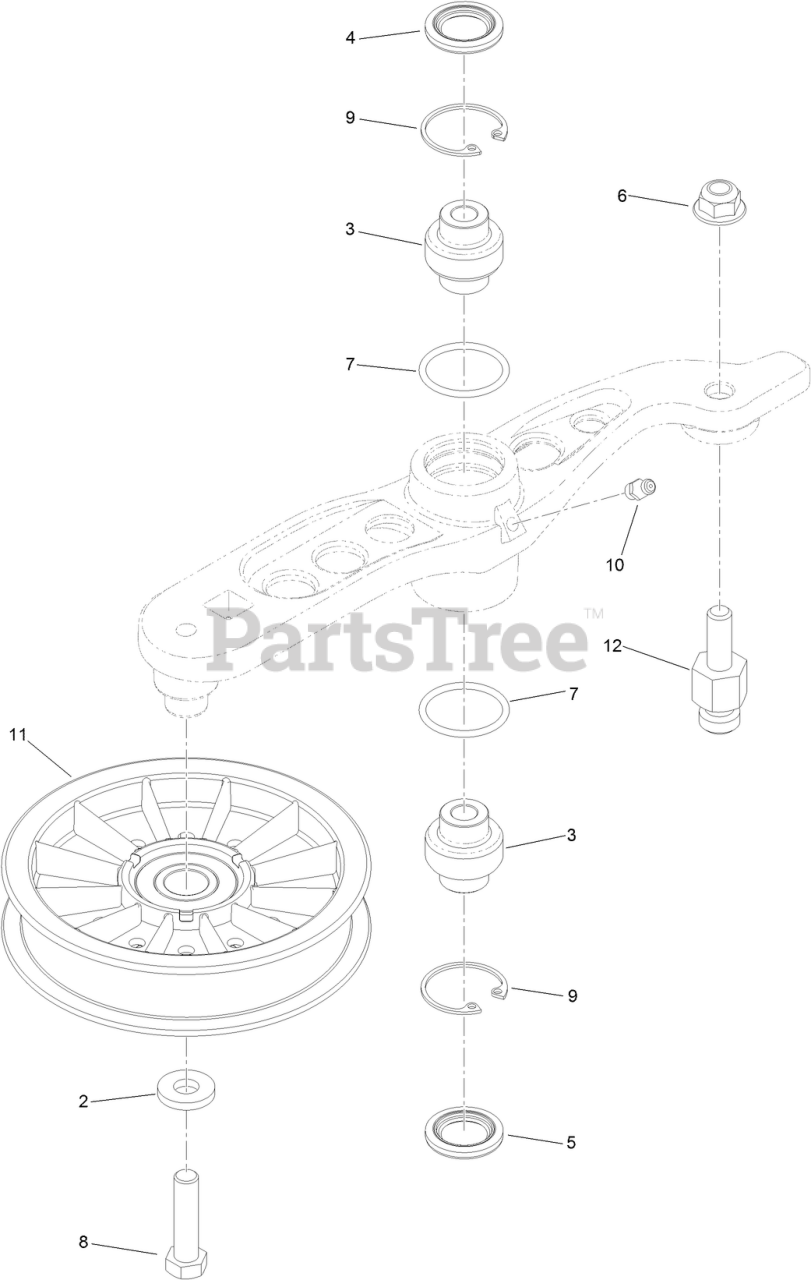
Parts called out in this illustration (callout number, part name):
3	BEARING-SPHERICAL
4	SEAL-LIP, DOUBLE
5	SEAL-LIP, SINGLE
6	Nut-Nyloc 3/8-16 Flg
8	SCREW-HH
9	RING-SNAP
10	FITTING-GREASE
11	PULLEY-IDLER
12	PIN-ANCHOR, SPRING
